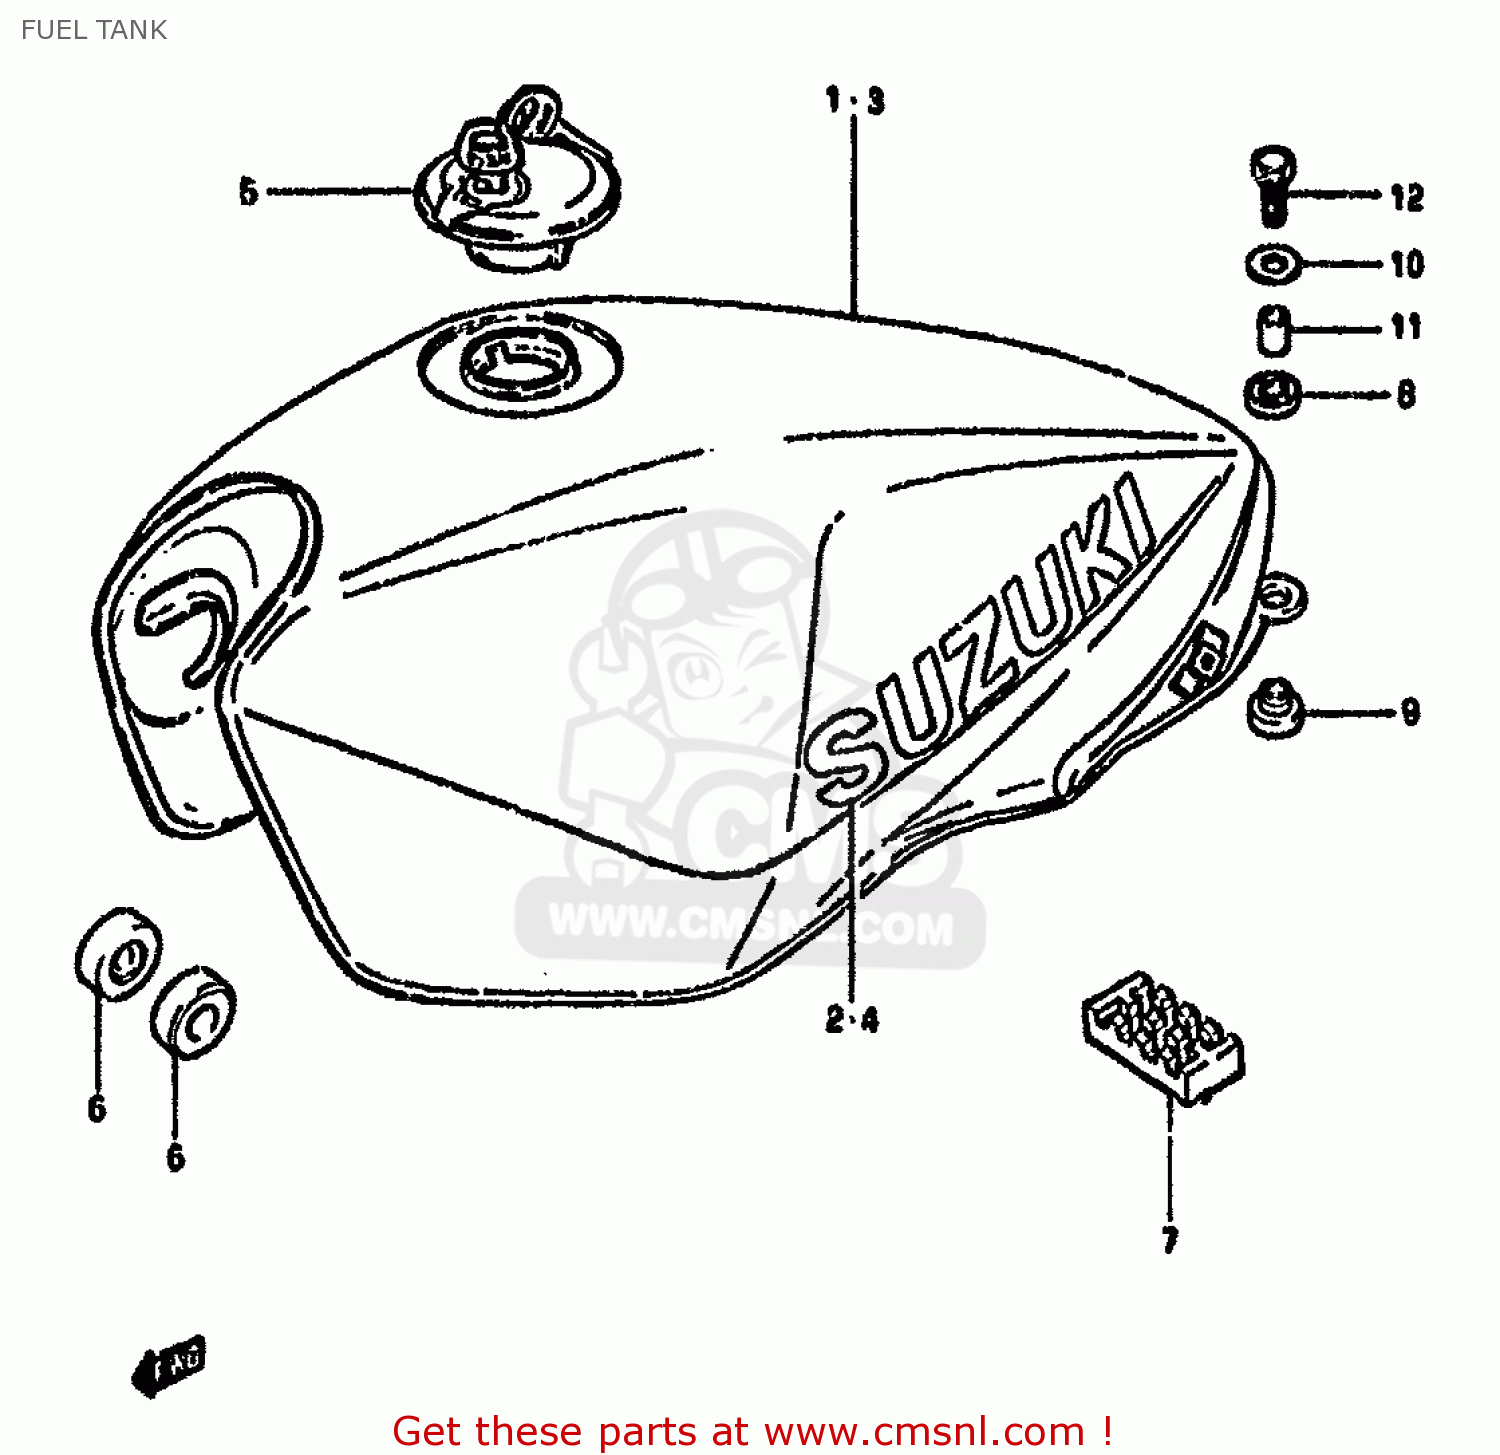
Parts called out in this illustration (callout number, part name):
1	TANK ASSEMBLY,FUEL
2	EMBLEM
3	TANK,FUEL (RED)
4	EMBLEM
5	CAP SET,FUEL TANK
6	CUSHION
7	CUSHION,FUEL TANK CTR
8	CUSHION
9	CUSHION
10	WASHER (6.5X24X1.6)
11	SPACER
12	BOLT
